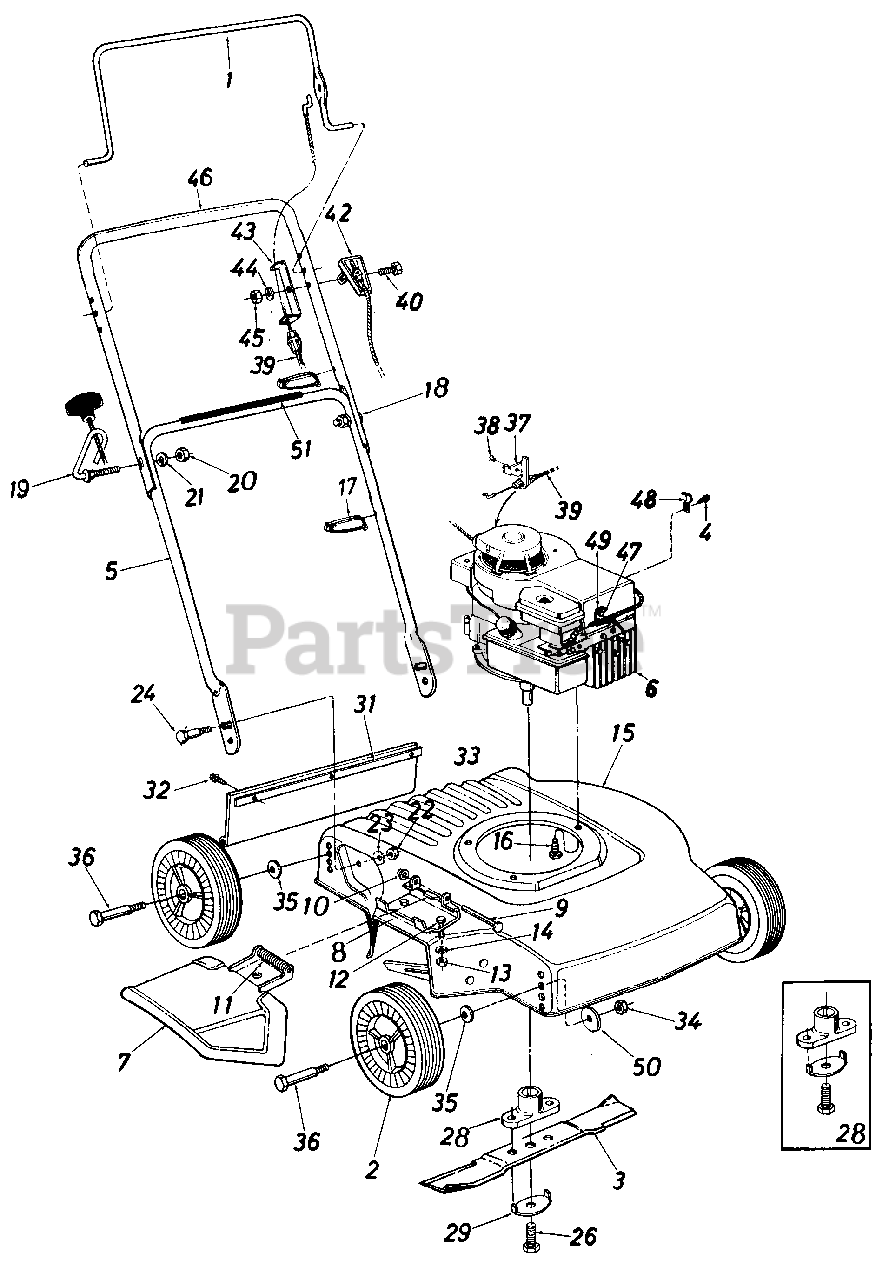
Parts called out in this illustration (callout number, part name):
1	Control Handle-L.H.
3	18" Blade
4	Hex Wash. Hd. AB-Tap Scr. #8 x .50" Lg.
5	Lower Handle (Chrome)
6	Engine
7	Chute Deflector Ass'y. Comp.
8	Adapter Plate
9	Pivot Pin
10	Push Nut 1/4" Rod
11	Torsion Spring
12	Hex Bolt 1/4-20 x .50" Lg.
13	Hex Nut 1/4-20 Thd.
14	L-Wash. 1/4" I.D.
15	18" Deck Ass'y.
16	Hex Wash. Hd. TT-Tap Scr. 3/8-16 x 1.00" Lg.
17	Cable Tie
18	Curved Carriage Bolt 5/16-18 x 1.38" Lg.
19	Rope Guide Bolt
20	Hex Nut 5/16-18 Thd.*
21	L-Wash. 5/16" I.D.
22	Hex Ins. L-Nut 5/16-18 Thd.
23	Bell-Wash. .345" I.D. x .88"
24	Shoulder Bolt .437" Dia. x .1 80
26	Hex Bolt 3/8-24 x 1.5" Lg. (Grade 5)
28	Blade Adapter Kit
29	Blade Bell-Washer
31	Retaining Strip
32	Hex Wash. Hd. AB-Tap Scr. 1/4" x.62" Lg.
33	Rear Flap Ass'y.
34	Hex Nut 3/8-16 Thd.
35	Bell-Wash. .400" I.D. x .88" O.D.
36	Shld. Bolt .498" Dia. x 1.450" Lg .
37	Cable Bracket
38	Pop Rivet .156" Dia. x .379
39	Control Cable-36"
40	Hex Bolt 1/4-28 x 1.75" Lg.
42	Throttle Control Ass'y. Comp.
43	Cable Mounting Brkt.
44	Spr. Wash. .27" I.D. x .57" O.D.
45	Hex Nut 1/4-28 Thd.
46	Upper Handle (Chrome
47	Hex B-Tap Scr. #10 x .38" Lg.
48	Casing Clamp
49	Casing Clamp
50	Fl-Wash. .398" I.D. x 1.13
51	Instruction Label-Handle
